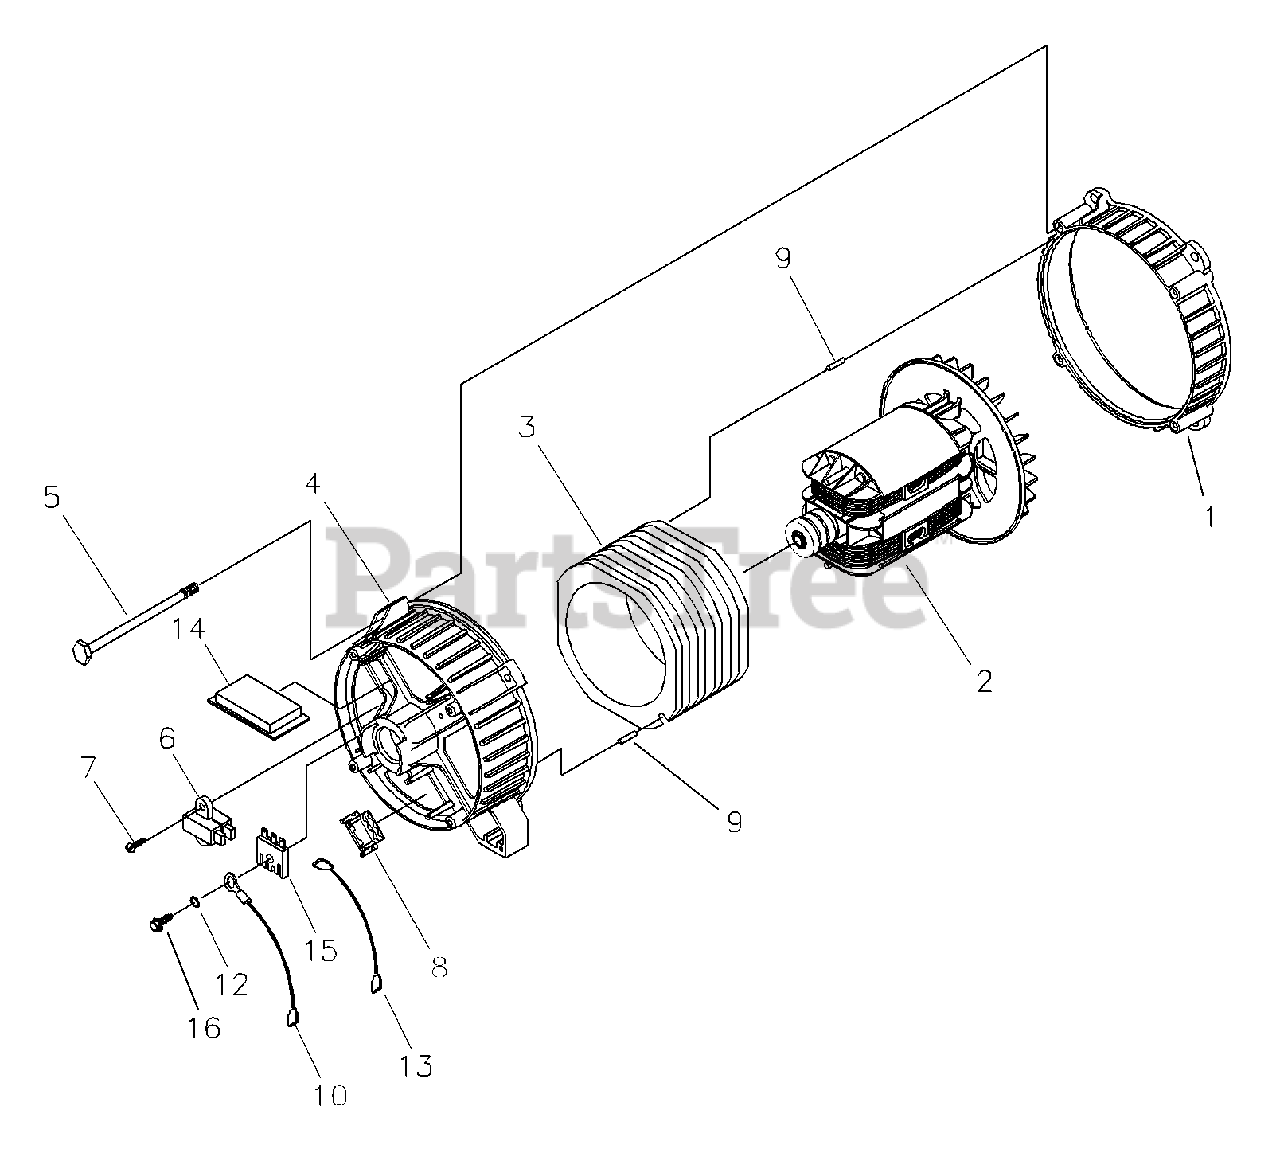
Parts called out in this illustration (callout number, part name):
1	ADAPTER, Mounting,Alternator
4	RBC, (with O-Ring, p/n 189197GS)
6	ASSY, Holder, Brush
8	RECEPTACLE, 6 pin
9	PIN, Roll
10	ASSY,Wire, Ground
13	WIRE, Ground
14	REGULATOR,Voltage,AVR
15	RECTIFIER
